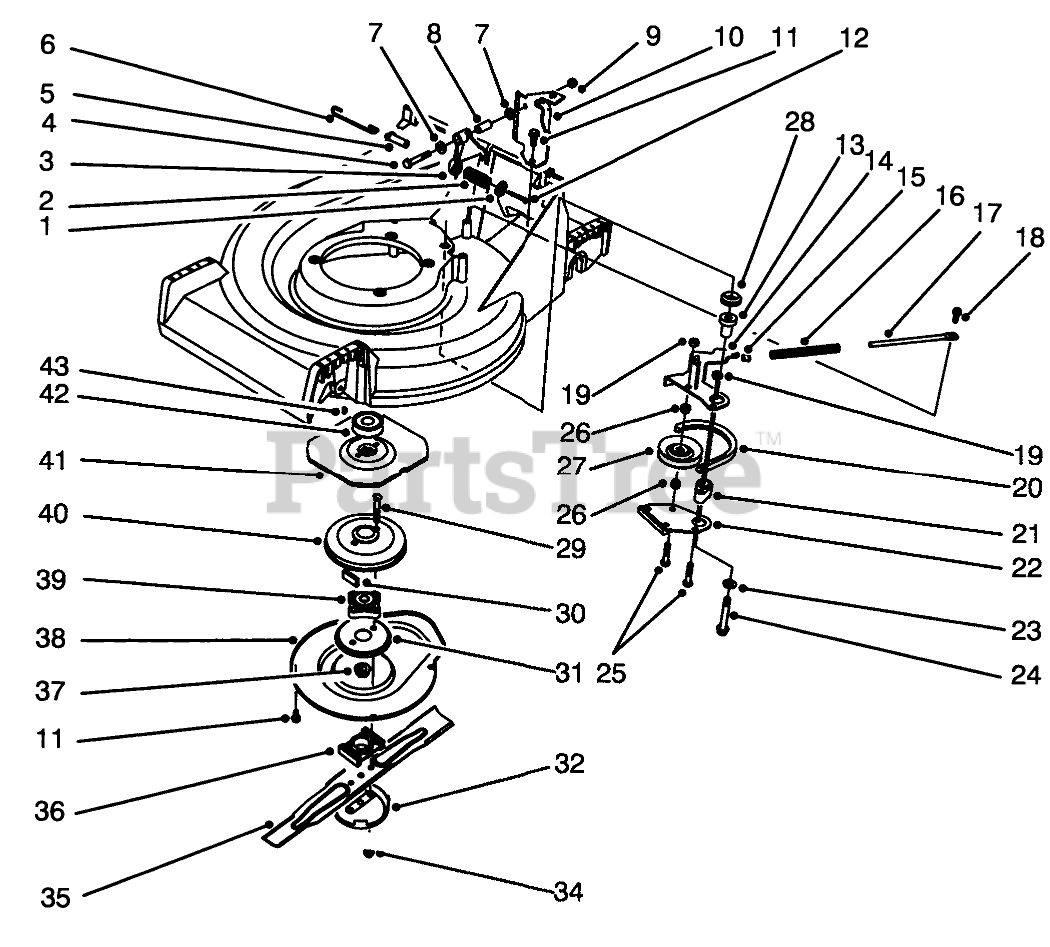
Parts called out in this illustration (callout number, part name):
1	RETAINER-SPRING
2	COMPRESSION SPRING
3	CRANK
4	SCREW-HH
5	SPRING PIN
6	CONTROL LINK
7	WASHER-PLAIN
8	STRAIGHT BUSHING
10	Bracket-Cable Support
11	SCREW-HWHTF
12	SCREW-HWHTF
13	BBC PM BUSHING
14	Lever
15	SPACER
16	COMPRESSION SPRING
17	SPRING ROD
18	SCREW-SHOULDER
19	NUT-LOCK, NI
20	V-BELT
21	BRAKE PLATE HUB
22	BRAKE SHOE
23	WASHER-PLAIN
24	THD FORM SCREW
25	SCREW-HH
26	IDLER PULLEY HUB
27	PULLEY-IDLER
28	V-RING SEAL
29	BOLT-BLADE
30	DAMPENER-VIBRATION
31	Screen-BBC
32	CUP-SCALP, ANTI
34	NUT-LOCK
35	Key
36	SPACER-BLADE
37	NUT-LOCK, NI
38	Cover
39	HUB ASM
40	BRAKE DRUM
41	FLYWHEEL - BBC
42	PULLEY
43	KEY-WOODRUFF
